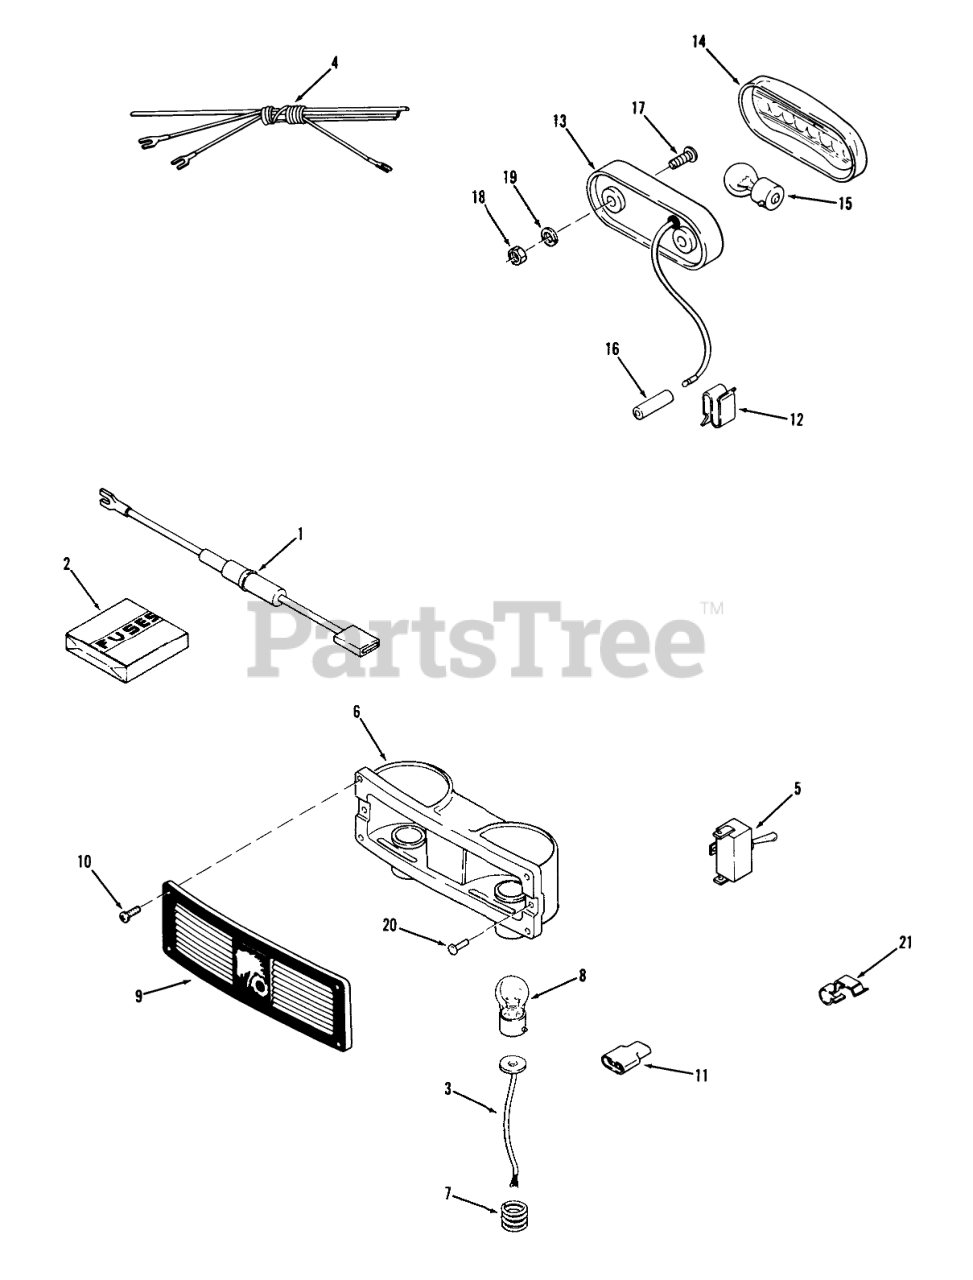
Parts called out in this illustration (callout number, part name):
1	ASSY FUSED CONNECTOR
3	WIRE ASSY
4	Wire Harness-Lights
5	SWITCH-LIGHTS
6	ASSY REFLECTOR HOUSI
7	SPRING
8	BULB
9	Lens
10	Pan HD Swage
11	CONNECTOR 3 WIRE
12	SPEED CLIP
13	Base-Taillight
14	Lens-Taillight
15	Bulb
16	CONNECTOR 2 WIRE
17	Screw
18	Nut
19	Lockwasher
20	RIVET
21	CLIP-WIRE
